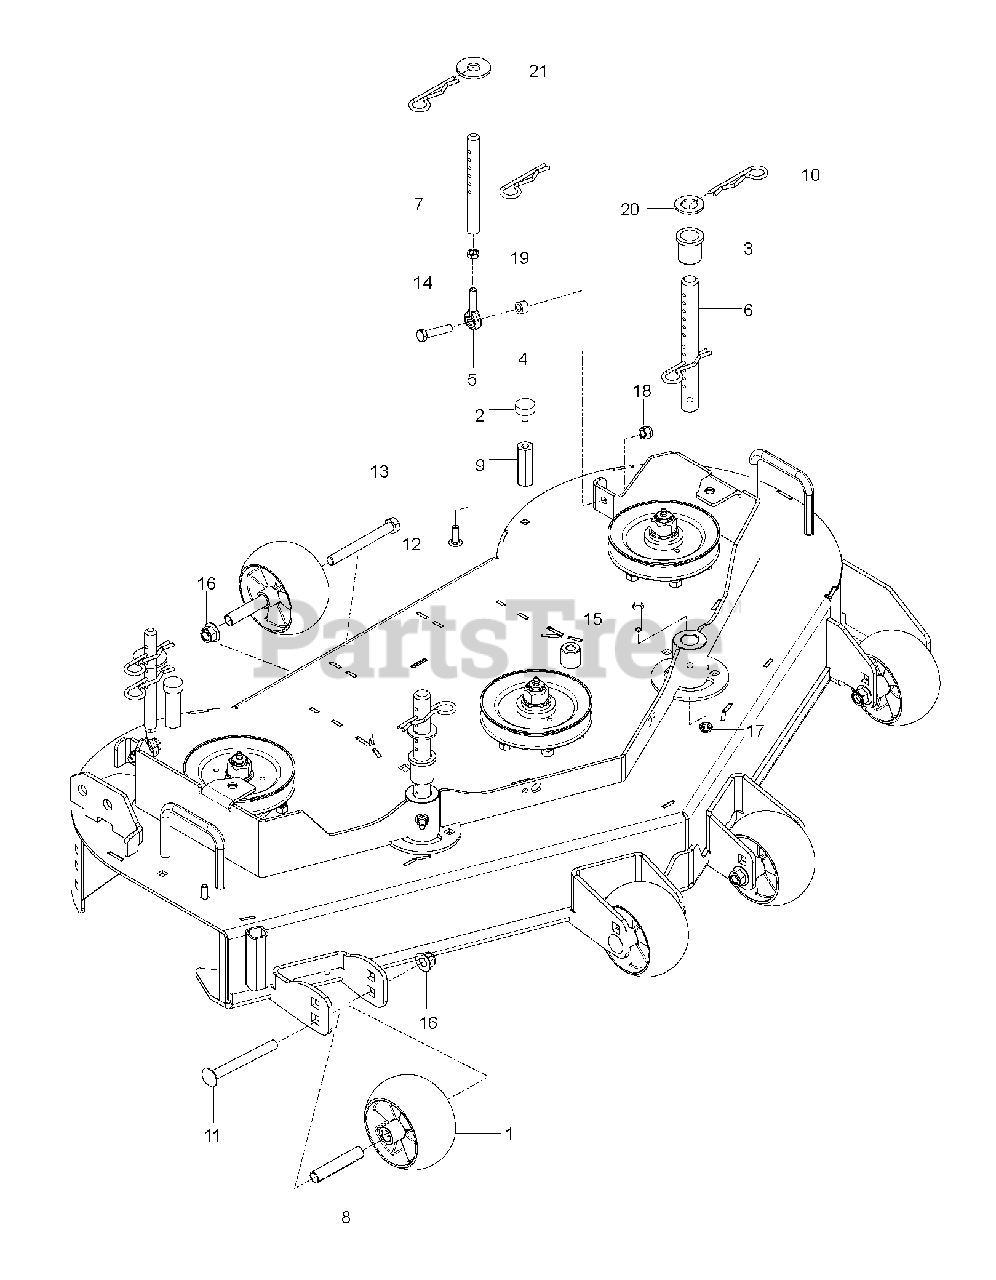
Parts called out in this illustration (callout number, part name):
1	WHEEL ANTI-SCALP WHEEL - 5X3 C
2	BUMPER RUBBER BUMPER 7533600
3	BUSHING BSHG-FLG 1.00X1.25X1.5
4	BUSHING BUSHING, SLV
5	ROD END 3/8 RH ROD END 8790600
6	PIN FRONT HOC 4197700
7	ROD REAR HOC ROD 3841021
8	SPACER .510X.625X3.35 SPACER 4
9	SERVICE PARTS SYSTEM COUPLER N
10	PIN PIN-HAIR-INT .17X.68X3.50
11	Round Head Bolt
12	SERVICE PARTS SYSTEM BOLT .31-
16	NUT NUT, LK-NYL-FLG .50-13 YWZ
17	SERVICE PARTS SYSTEM NUT-SPNLK
18	NUT NUT, 3/8-16 NYLON LOCK ARI
19	SERVICE PARTS SYSTEM NUT-JAM .
20	SERVICE PARTS SYSTEM WASHER, F
21	SERVICE PARTS SYSTEM WASHER, F
